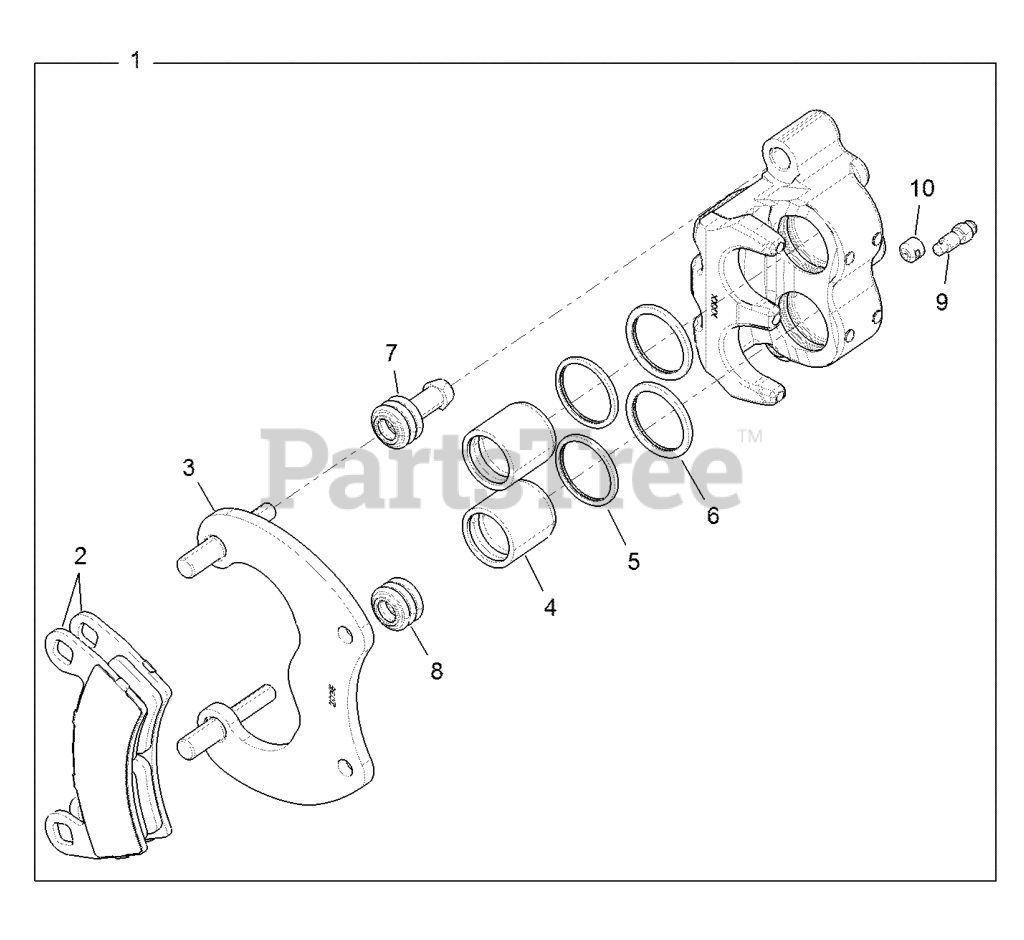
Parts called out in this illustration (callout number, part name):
1	ASM-CLPR,DB1.18,LH,GROOVED
1	ASM-CLPR,DB1.18,RH,GROOVED
2	KIT, BRAKE PAD
3	ASM-CALIPER MNT,DB,3.0",APX
4	PISTON-BRAKE,1.188",AL,GROOVED
5	RING,SQUARE,MOLDED,.094
6	RING,SQUARE,MOLDED,.103X.134
7	BOOT-PIN BUSHING
8	BOOT-PIN SEAL
9	SCR-M7X1.0,BLEEDER,OLIVE D
10	SCR-M10X1.0X8,SOC SET-OD
